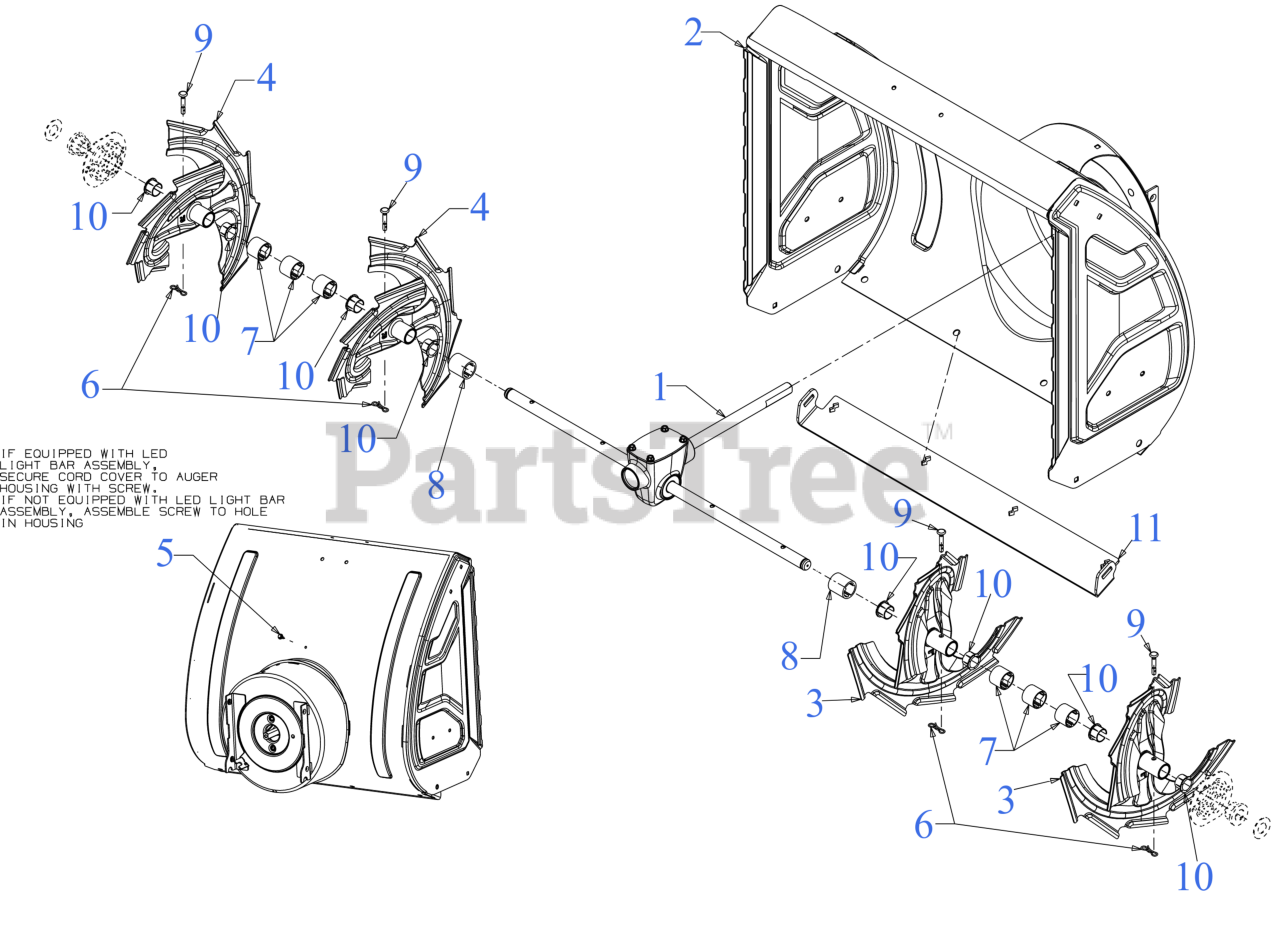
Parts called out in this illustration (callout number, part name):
1	28" AUGER GEARBOX ASSEMBLY
2	28" AUGER HOUSING (HD/LED)
3	10T AUGER SPIRAL (LH)
4	10T AUGER SPIRAL (RH)
5	SCREW M6-1 x .625
6	BOW TIE COTTER PIN 1/4-5/16
7	SPACER 1.25OD x .75ID X1.00 LG
8	SPACER 1.25OD x .75ID x 1.312 LG
9	SHEAR PIN .25 x 1.50 GR2
9	Cub Cadet SHEAR PINS (2X SNOW)
9	SHEAR PINS QTY 4
10	FLANGE BUSHING
